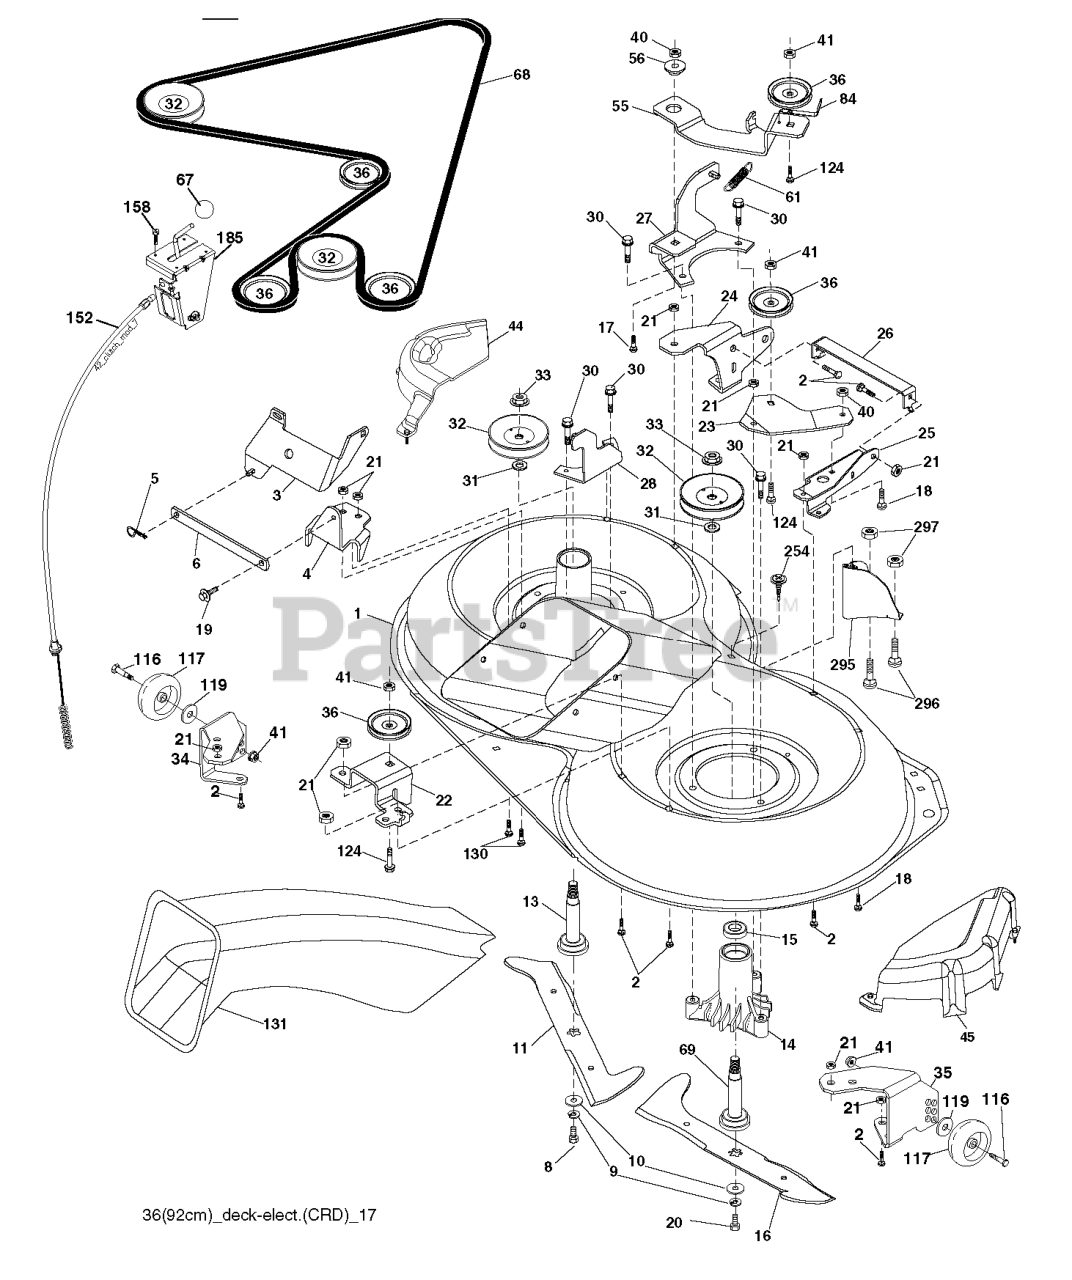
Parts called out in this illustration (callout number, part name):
2	RP BOLT 5/16-18 X3/4 ZN/YEL GR
3	BRACKET.ASM.BAR.SWAY.CHASS
5	RETAINER-SPRNG RB
6	BAR.SWAY.92.CRD
8	BOLT.3/8-24X1.25 GR8
9	LOCKWASHER
10	WASHER.BLADE
13	SHAFT ASM VENT
14	HOUSING.MANDREL.VENTED (MACHD)
17	BOLT.3/8-14X1.25
19	BOLT SHD 5/16-18
20	BOLT.3/8-24X1.25GR8. LHTHRD
21	LOCKNUT
26	SUPPORT
30	SCREW, WASHER HEAD
31	WASHER.SPACER.MANDREL
32	PULLEY MANDREL
33	NUT.FLANGE.LOCK.TOP
36	PULLEY.IDLER.4.25
41	NUT LOCK FLG 3/8-16 UNC
55	ARM.IDLER.92 CRD.2006
56	SPACER.RETAINER.MOWER
61	SPRING
67	KNOB T (3/8 HOLE)
68	BELT.DRIVE.92CM.CRD.2006
69	SHAFT.ASM.W/LWR.BRG.RH.THREAD
84	KEEPER, BELT IDLER
116	BOLT.SHOULDER.3/8-16X3-5/8.
117	RP WHEEL. GUAGE RALLY
119	WASHER
124	BOLT.3/8-16X1.50
130	BOLT.CARR.SQNK.5/16-18UNC.X3/4
131	CHUTE BAGGER
158	SCREW
185	HEAD ASM. CABLE CLUTCH
254	SCREW 3/8-16X1
296	BOLT
297	NUT CENTERLOCK
